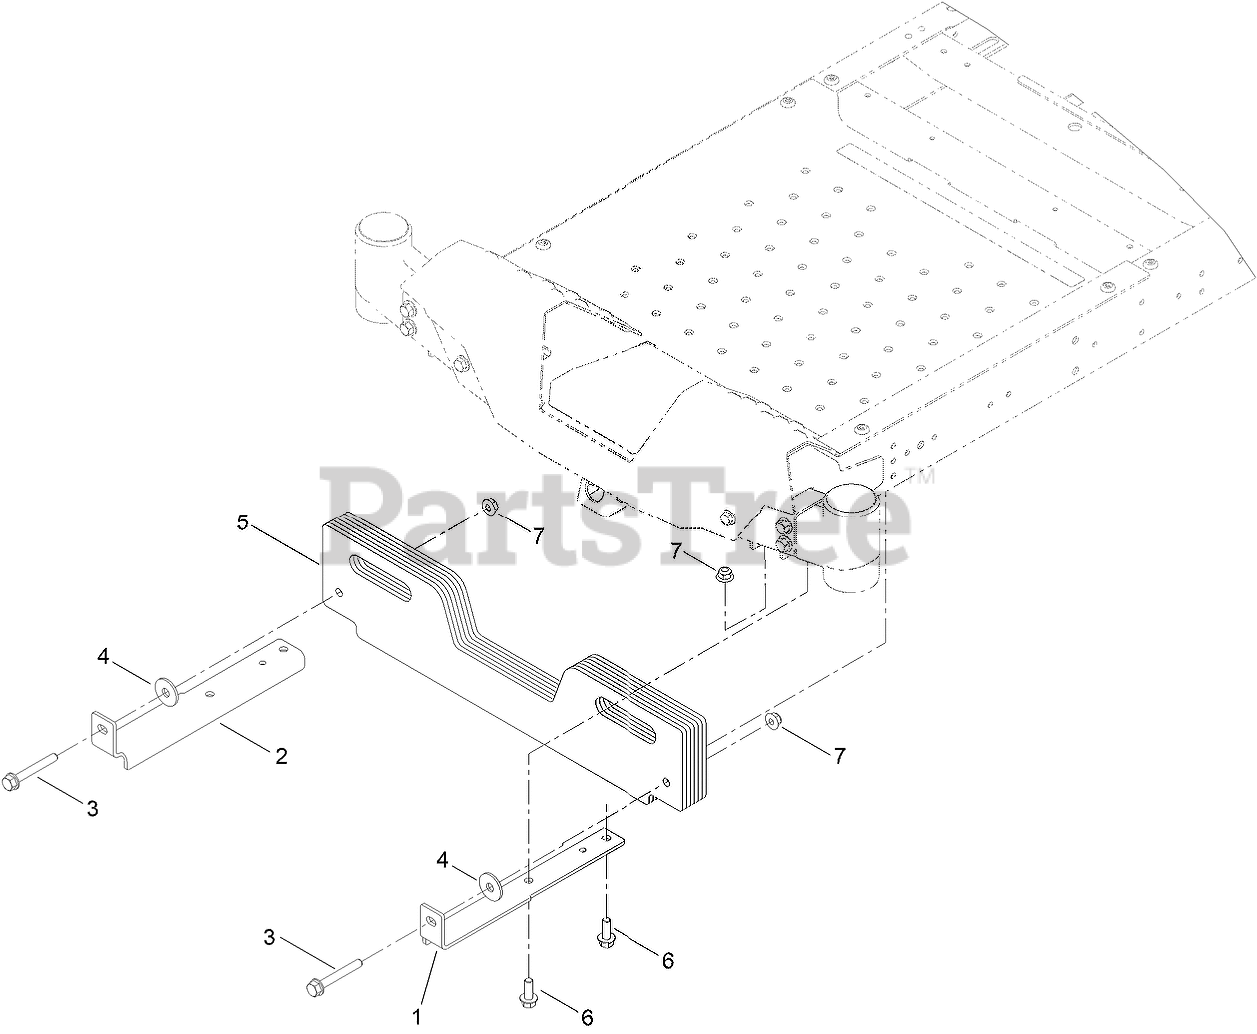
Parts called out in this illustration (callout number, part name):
1	Bracket-Weight, LH
2	Bracket-Weight, RH
3	Screw-Spcl
5	Weight-Bagger
6	SCREW-HHF
7	Nut-HF, NI
